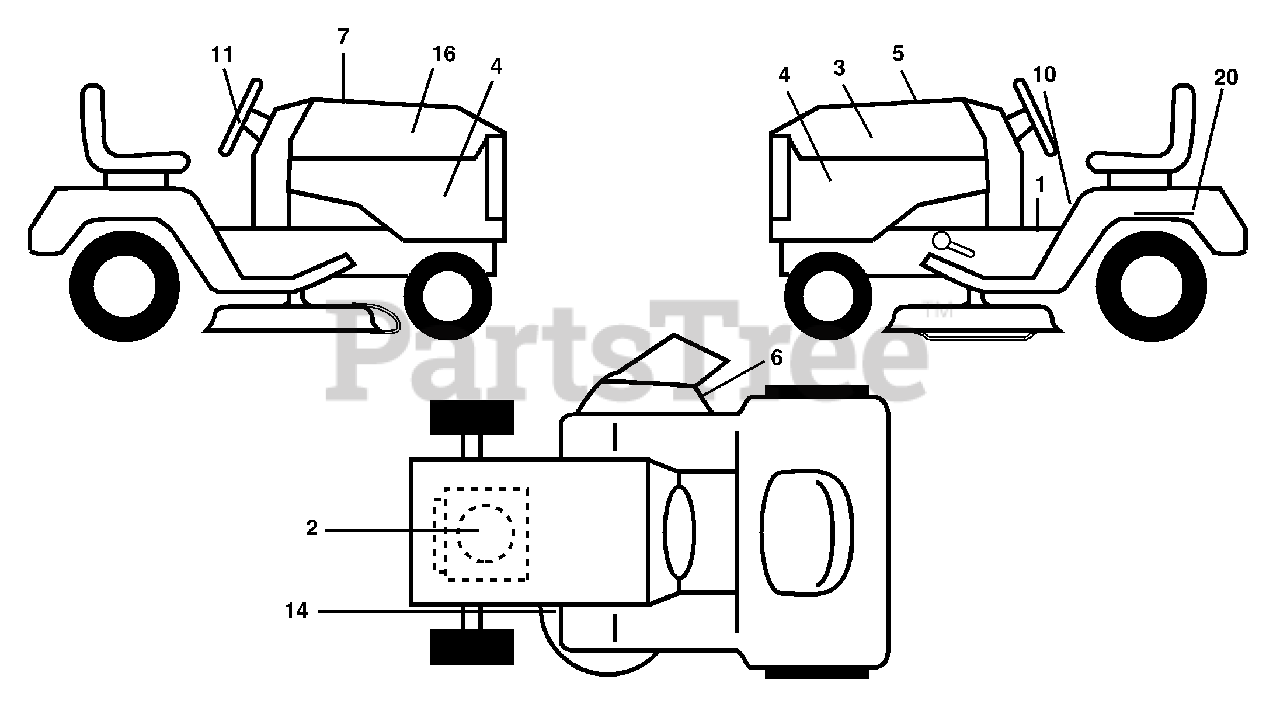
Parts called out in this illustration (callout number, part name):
1	Decal Oper
2	Decal Engine HP
3	Decal Hood LH
4	Decal Side Panel Logo
5	Decal Hood Cust Resp.
6	Decal Warning, Keep Hand Away
7	Decal Replacement Parts
10	Decal Fender Danger E/F
11	Decal Ins Strg Whl
14	Decal V-Belt Schematic
16	Decal Hood Rh
20	Decal Bat Dan/Psn
